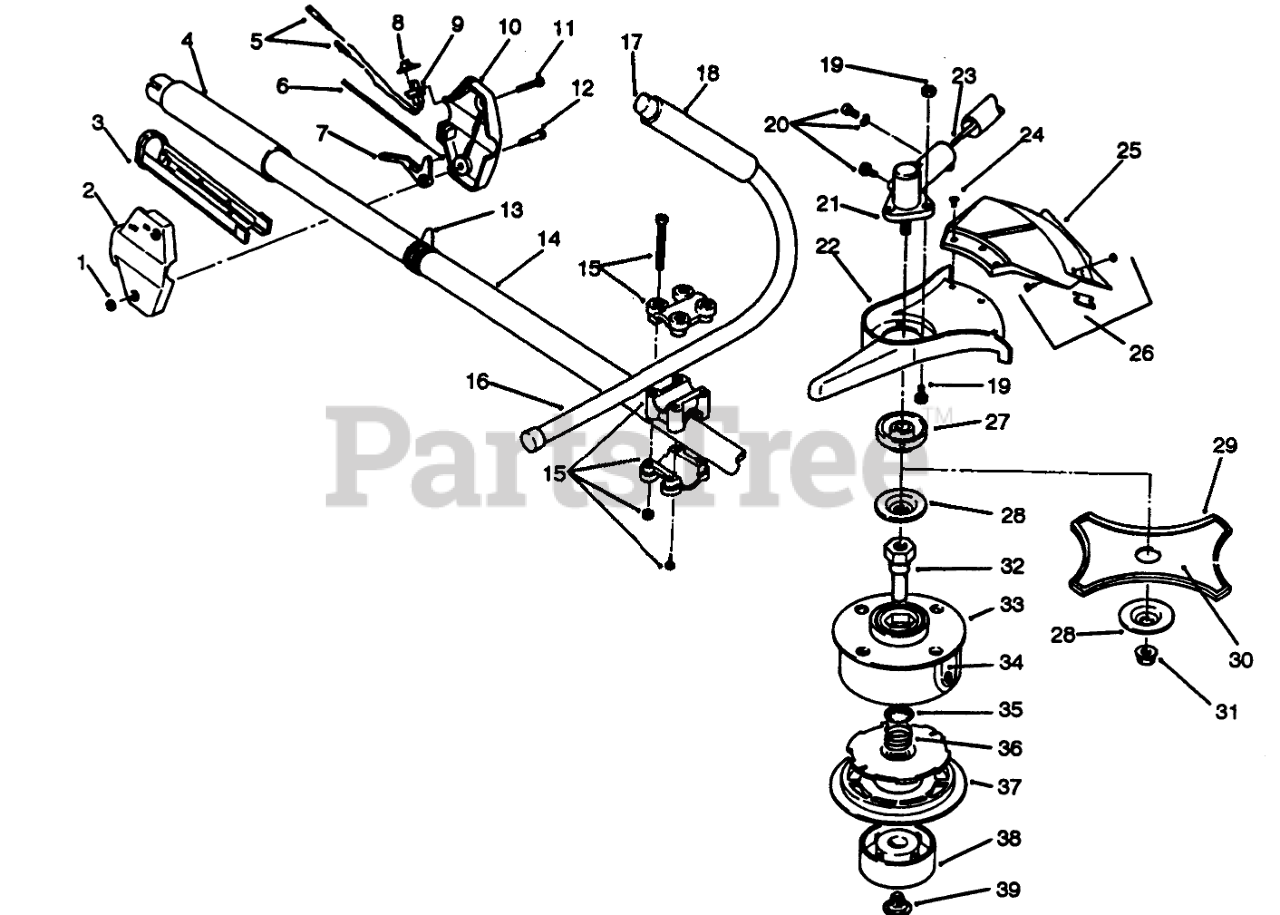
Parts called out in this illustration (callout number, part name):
1	NUT-LOCK, NI
2	RH HOUSING
3	TROUGH 1"
4	GRIP - RUBBER
5	LEAD WIRE ASM
6	THROTTLE CABLE
7	THROTTLE LEVER
8	SWITCH COVER
9	SWITCH
10	LH HOUSING
12	SCREW-SHOULDER
13	Clip-Shoulder Strap
14	DRIVE SHAFT HSG ASM
15	Assy.-Bracket, Handle (Incl. 4 Screws & 4 Nuts)
16	Assy.-J-Handle (Incl. Ref. No.17 & 18)
17	TUBE CLOSURE
18	HANDLE NITRILE GRIP
19	SCREW
20	MTG HDW&PLUG SET
21	Assembly-Gear Box (Incl. Ref. No.27 & 28)
22	GUARD MOUNT
23	FLEXIBLE DRIVE SHAFT
24	GUARD MNTG SCREW ASM
25	Assy Guard & Blade (Incl. Ref. #26)
26	Assembly-Blade (Incl. 2 Screws & 2 Nuts)
27	Driver-Blade
28	Blade Retaining Washer
29	BLADE SAFETY GUARD
30	Blade (Incl. Ref. No.29)
31	BLADE RETAINER NUT
32	SPOOL SHAFT
33	Outer Spool & Eyelet Asm.
34	EYELET
35	RETAINER ( 10 PACK)
36	SPRING
37	INNER REEL
38	Assy.-Bump Head
39	Bolt-Bump Head
